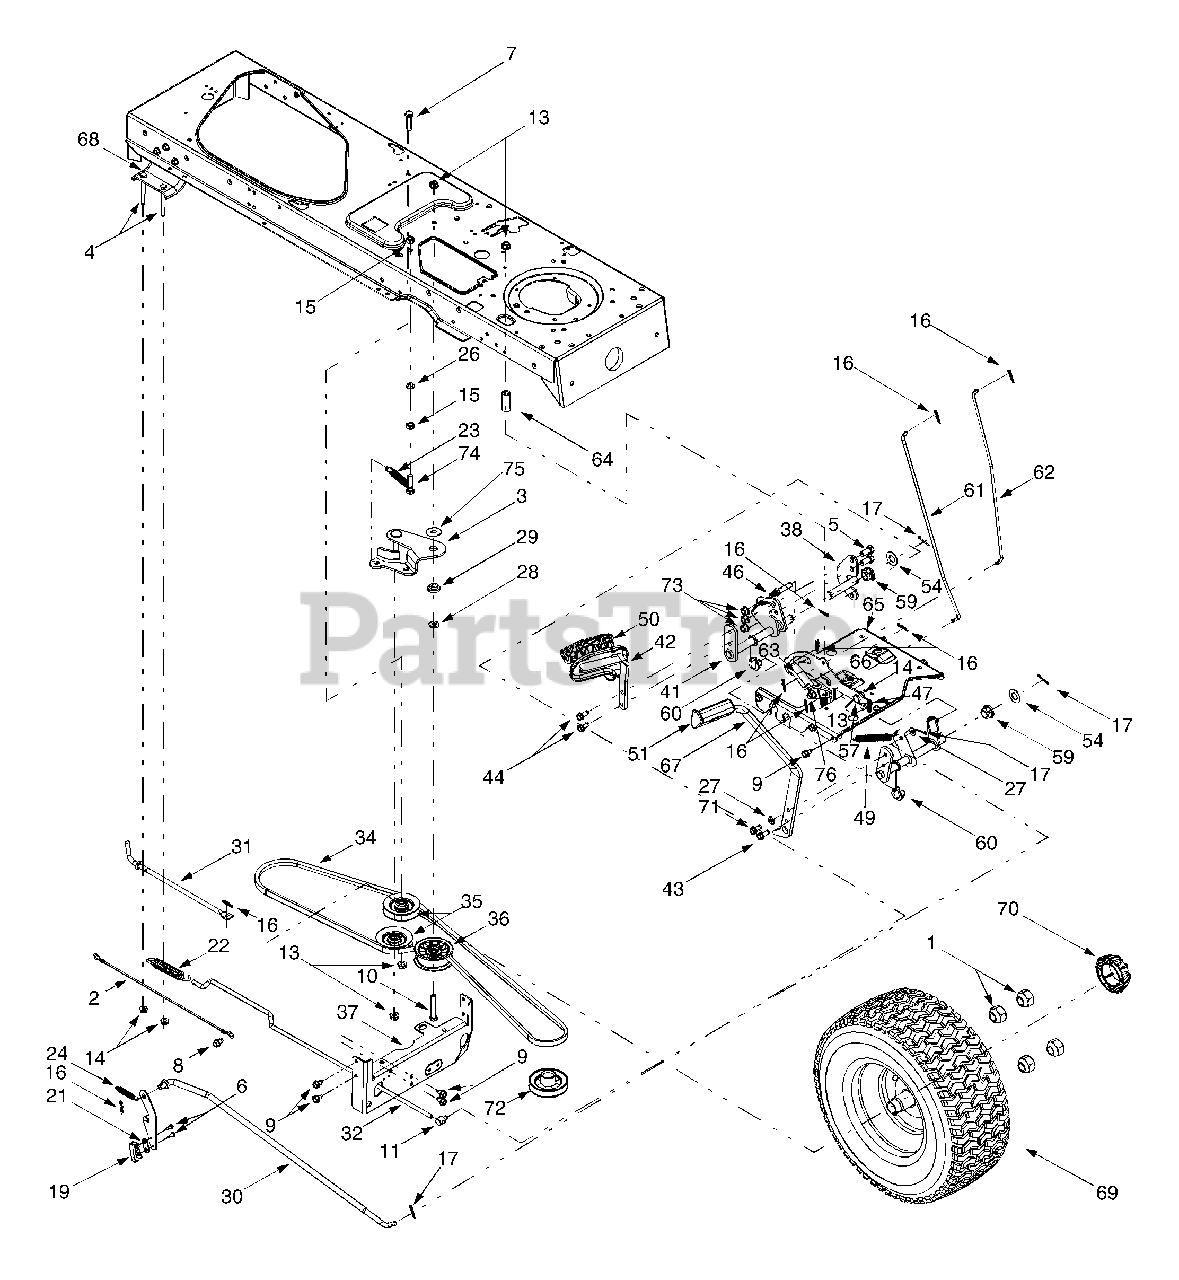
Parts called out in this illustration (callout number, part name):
1	Lug Nut, 3/4-16
2	Reverse/Ground Wire Harness Adapter
4	Hex Cap Screw, 5/16-18 x 2.75
5	Hex Cap Screw, 3/8-16 x.75
6	Screw, #8-18 x.5
7	Hex Cap Screw, 3/8-16 x 1.5
8	Self-tapping Screw, 1/4-20 x.50
9	Self-tapping Screw, 5/16-12 x.75
10	Hex Cap Screw, 3/8-16 x 2.25
12	Ferrule, 3/8-24
13	Flange Lock Nut, 3/8-16
14	Flange Lock Nut, 5/16-18
15	Hex Nut, 3/8-16
16	Internal Cotter Pin
19	Short Spring Switch
20	Push-mount Cable Tie
21	Insulator Nut Plate
22	Extension Spring,.59 x 4.0
23	Extension Spring,.5 x 3.97
24	Extension Spring, 3/8 x 1.44
26	Lock Washer, 3/8
27	Flat Washer,.344 x.750 x.120
28	Flat Washer,.407 x.812 x.135
29	Shoulder Spacer,.38
30	Hydrostatic Control Rod
31	Hydrostatic Bypass Rod
32	Hydrostatic Brake Rod
34	Drive Belt
35	V-idler Pulley, 3.06
36	Flat Idler Pulley, 2.75
43	Self-tapping Screw, 5/16-18 x.875
44	Self-tapping Screw, 5/16-18 x.75
46	Pin, 3/8-16 x 2.43
47	Compression Spring,.40 OD x 1.17
48	Extension Spring,.50 OD x 1.41
49	Extension Spring,.50 OD x 6.37
50	Drive Pedal Pad
51	Brake Pedal Pad
54	Flat Washer,.64 x 1.24 x.06
56	Flat Washer,.406 x.875 x.105
57	Shoulder Screw,.437 x 1.62
59	Hex Flange Bearing
60	Split Hex Flange Bearing
61	Cruise Control Rod
62	Brake Lock Control Rod
63	Cruise Latch
64	Spacer, 5/16 x 1.54
66	Drive Lockout Bracket
70	Hub Cap
71	Self-tapping Screw, 5/16-18 x.75
72	Engine Pulley
73	Flange Lock Nut 3/8-16
74	Hex Cap Screw, 3/8-16 x 1.5
75	Flat Washer.38 x 1.38 x.125
76	Shoulder Screw 3/8-16.50 x.27
